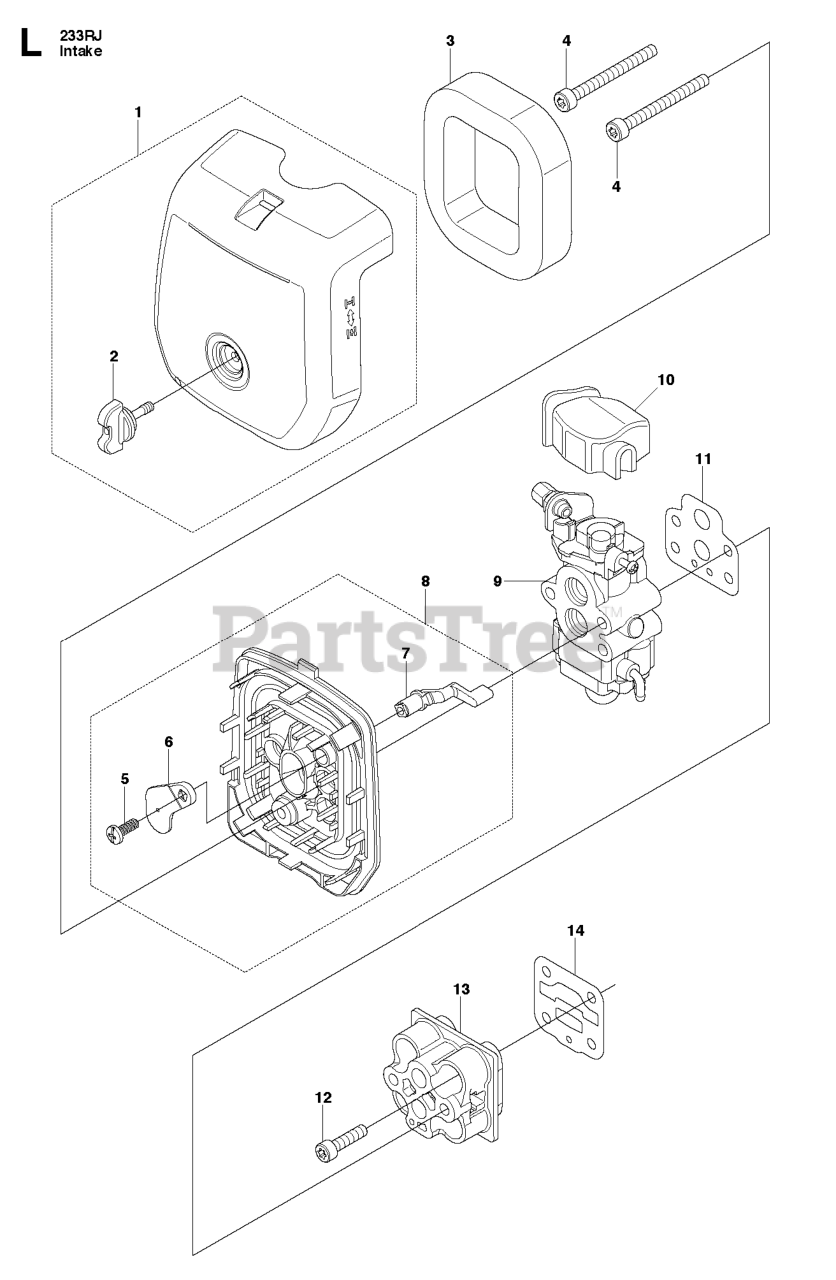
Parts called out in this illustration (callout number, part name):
2	KNOB
3	ELEMENT
4	BOLT TORX M5XL50 T27
5	SCREW
6	PLATE
7	LEVER CHOKE
11	GASKET, CARB (RPLS T155113131)
12	BOLT, TORX
